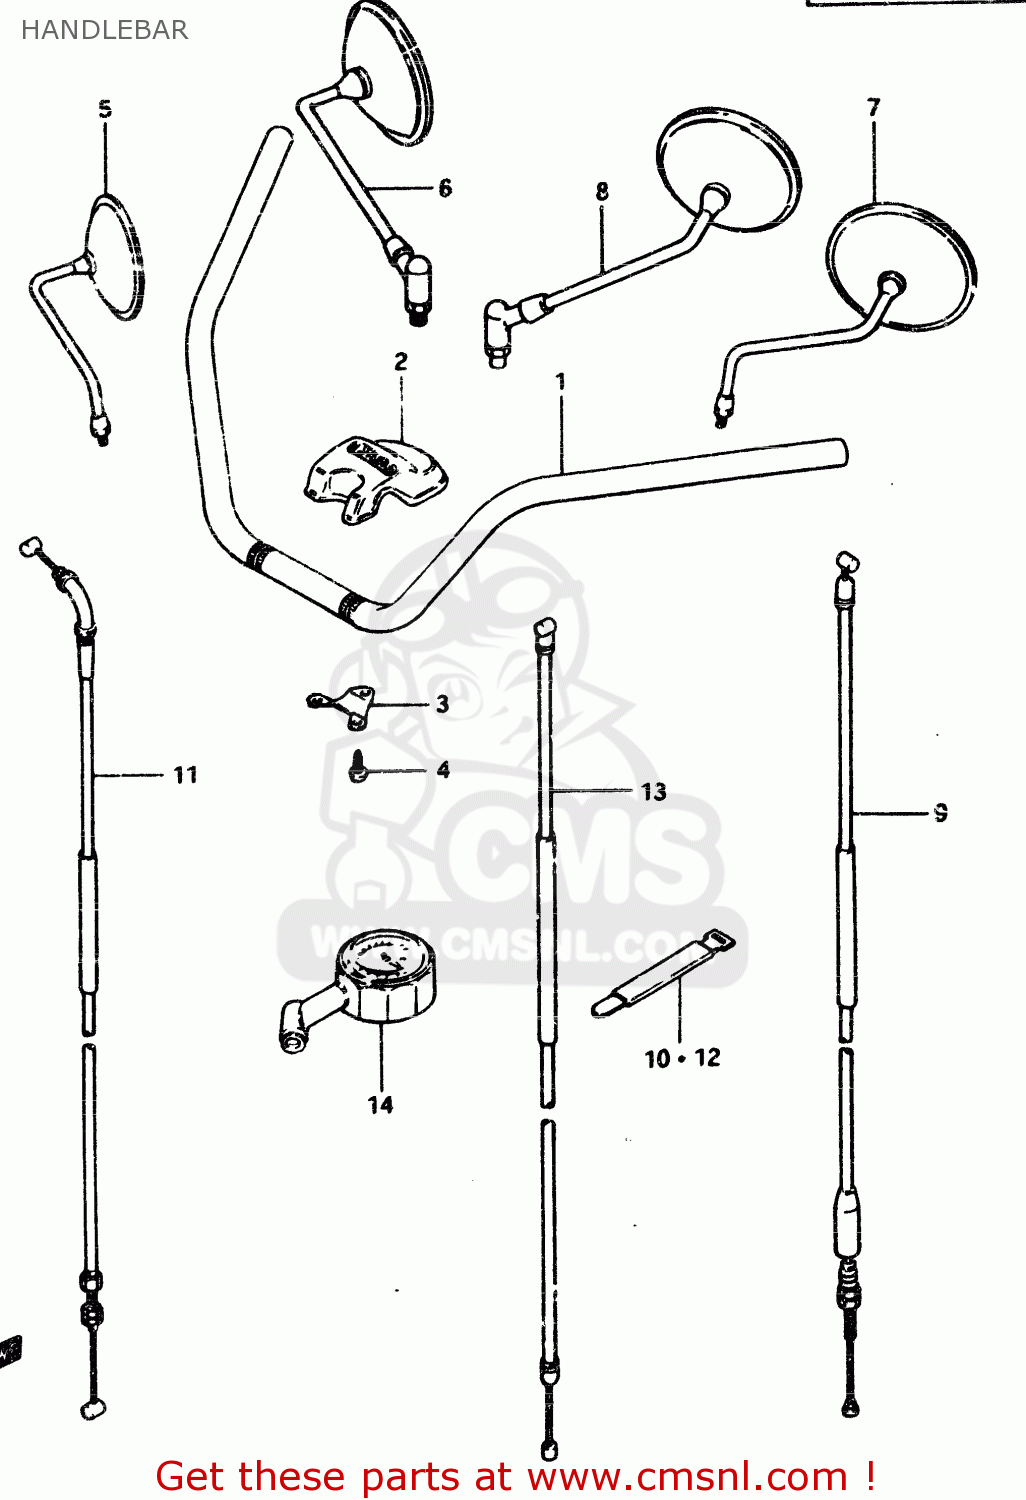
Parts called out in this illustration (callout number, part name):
1	HANDLEBAR
2	COVER,STEERING HEAD
3	BRACKET,HEAD COVER
4	SCREW
5	MIRROR ASSEMBLY,RIGHT
6	MIRROR, REAR VIEW RH
7	MIRROR ASSEMBLY,LEFT
8	MIRROR, REAR VIEW LH
9	CABLE ASSEMBLY,CLUTCH
10	CLAMP
11	CABLE ASSEMBLY,THROTTLE
12	CLAMP
13	CABLE ASSEMBLY,STARTER
14	GAUGE ASSY,AIR PRESSURE
